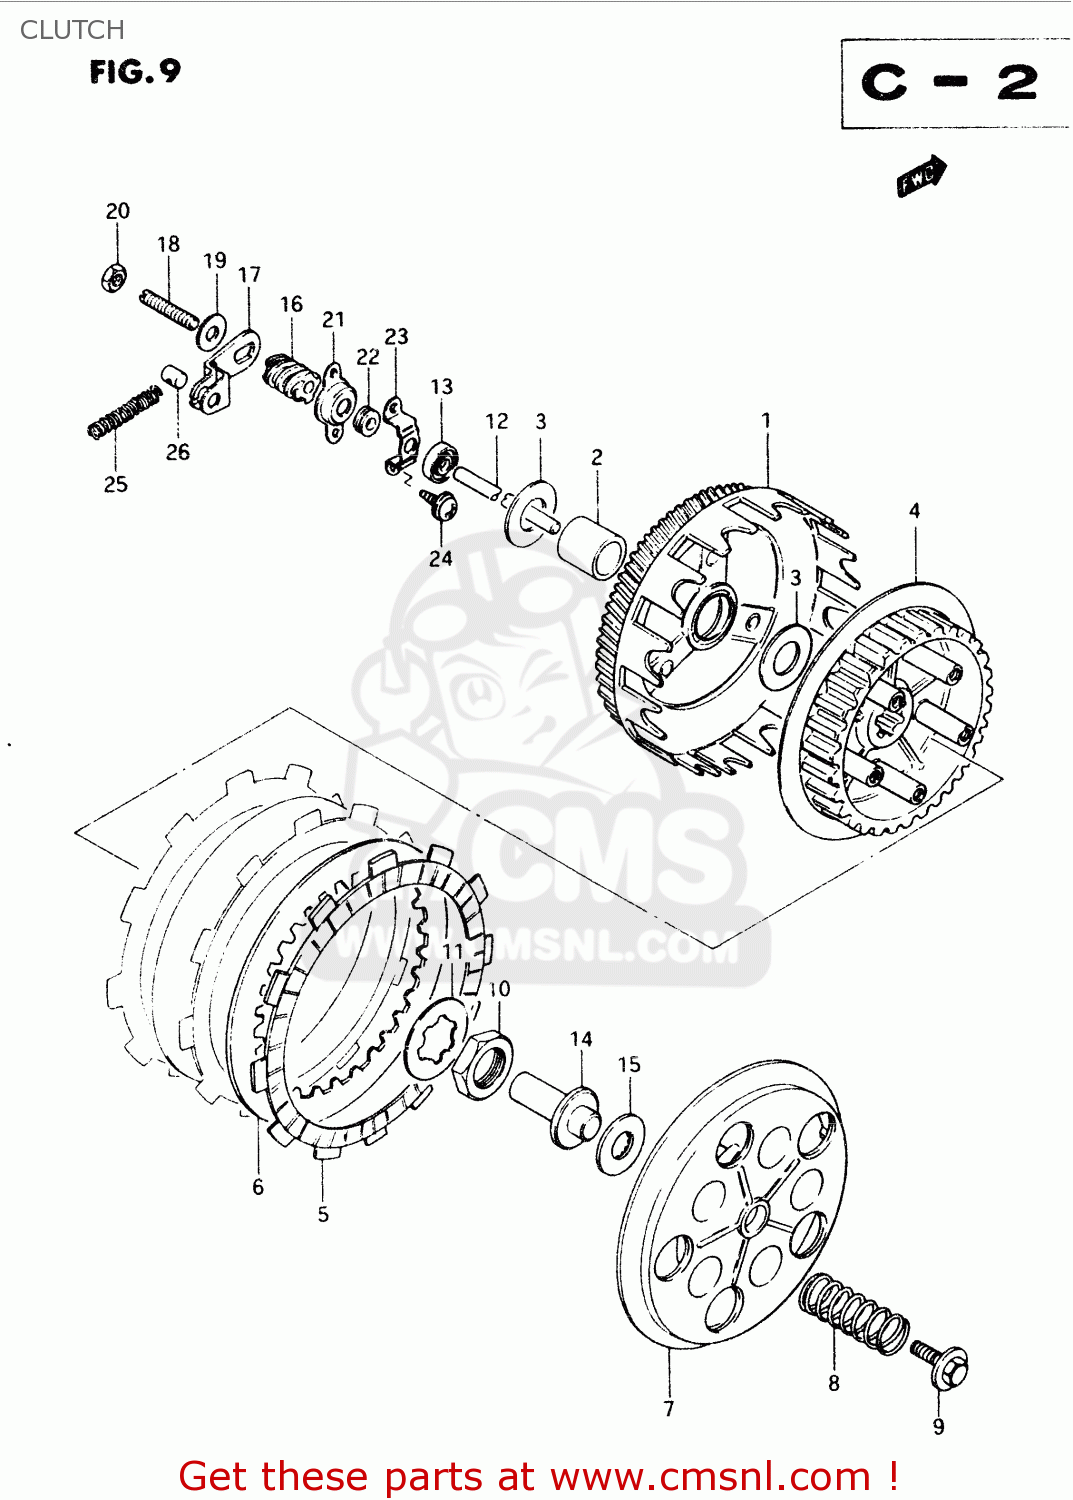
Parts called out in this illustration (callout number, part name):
1	GEAR ASSY, PRIMARY DRIVEN
2	SPACER(17X22X28.5)
3	WASHER
4	HUB,CLUTCH SLEEVE
5	PLATE,CLUTCH DRIVE (NAS)
6	PLATE,CLUTCH DRIVEN (NAS)
7	DISC,CLUTCH PRESSURE
8	SPRING
9	BOLT 5X16
10	NUT
11	WASHER,LOCK
12	ROD,CLUTCH PUSH
13	SEAL,OIL(5.5X16X8)
14	PIECE,CLUTCH PUSH
15	BEARING(10X22X2.8)
16	SCREW,CLUTCH RELEASE
17	ARM,CLUTCH
18	SCREW(6X25)
19	WASHER(6.5X20X1.6)
20	NUT
21	COVER,CLUTCH RELEASE SCREW
22	SEAL,DUST(5.3X13X5)
23	HOLDER,DUST SEAL
24	SCREW
25	SPRING
26	PIECE,RELEASE
